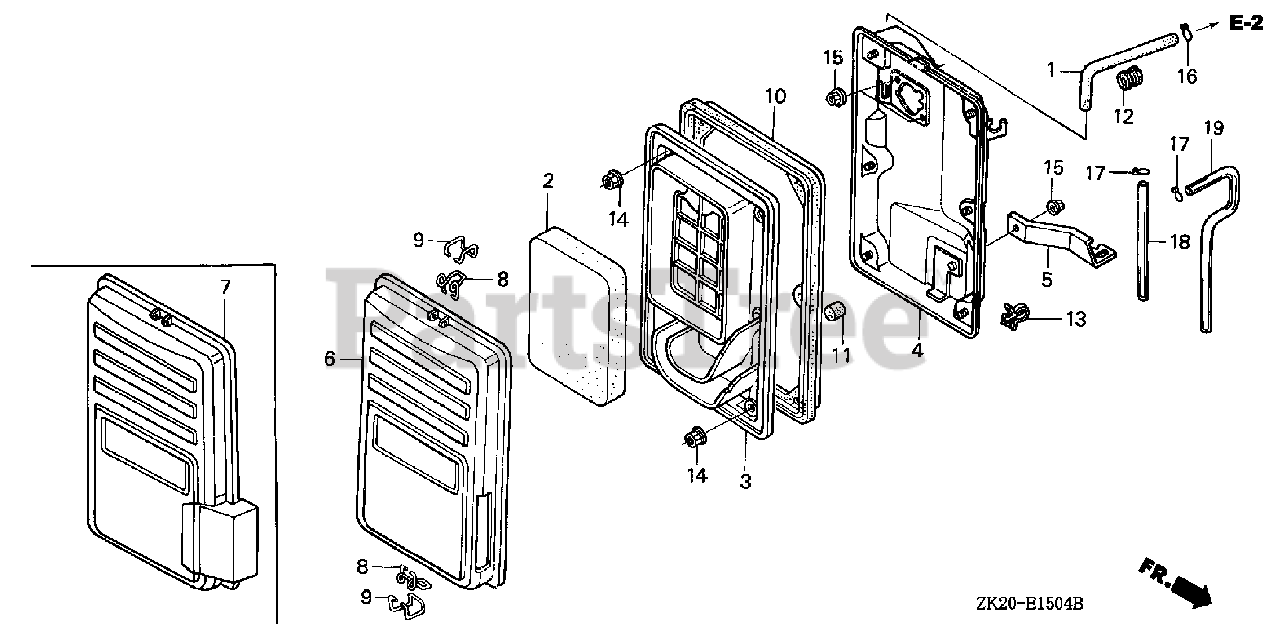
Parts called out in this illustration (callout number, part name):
1	TUBE, BREATHER
2	ELEMENT, AIR CLEANER
3	SEPARATOR, AIR CLEANER
4	HOUSING, AIR CLEANER
5	STAY, AIR CLEANER
7	COVER, AIR CLEANER
8	CLIP A, AIR CLEANER WIRE
9	CLIP B, AIR CLEANER WIRE
10	SEAL, AIR CLEANER
11	FILTER, DRAIN TUBE
14	NUT, FLANGE (5MM)
15	NUT, FLANGE (6MM)
